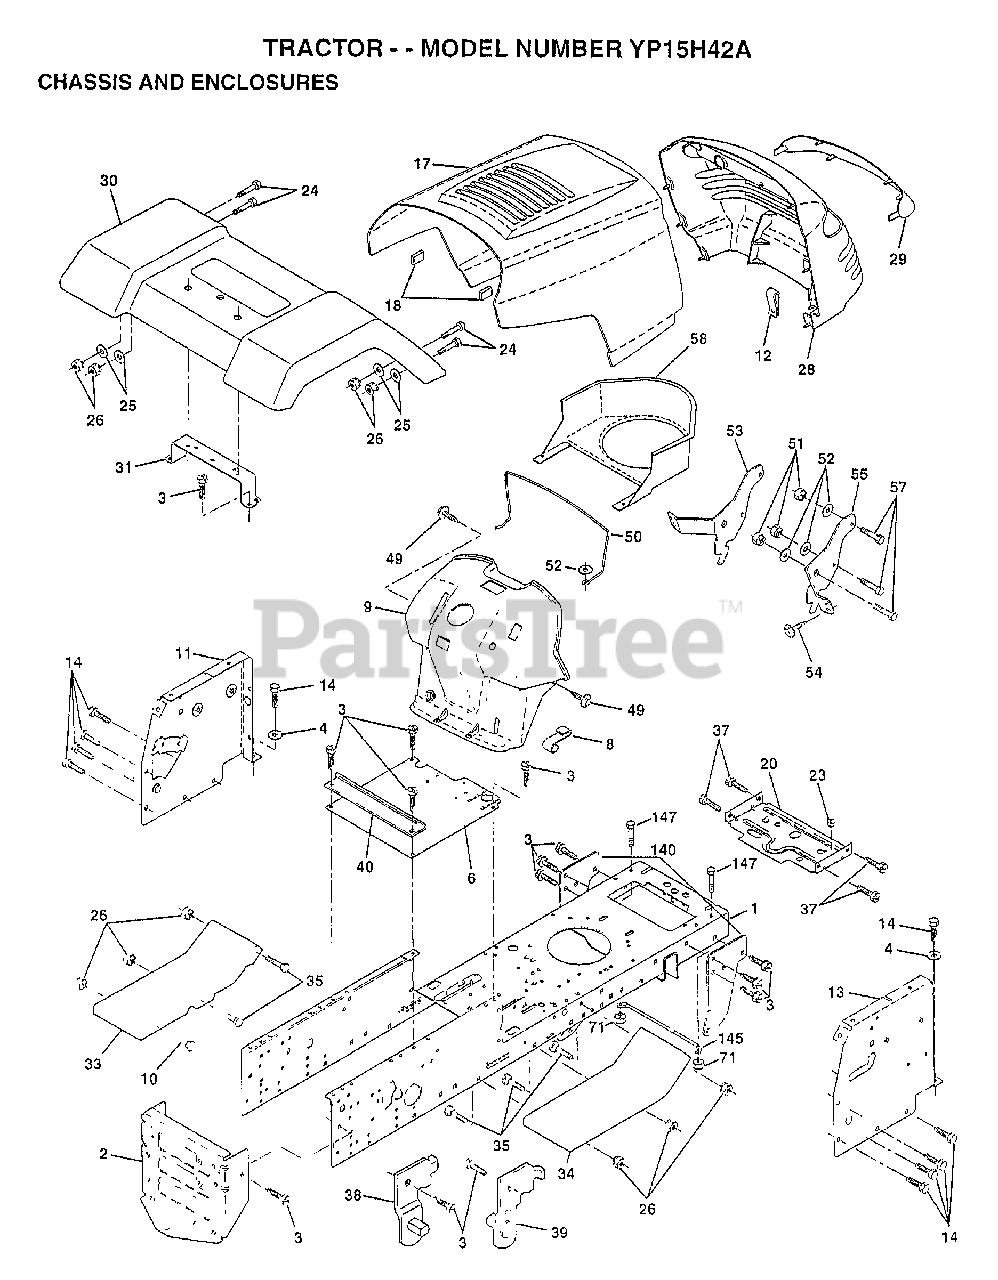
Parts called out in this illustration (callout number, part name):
1	CHASSIS ASM
3	SCREW
4	WASHER
6	SADDLE
8	CLIP.RETAINER
9	DASH.PRVT.LBL.
11	"PANEL-DASH,LH"
12	CLIP.TINNERMAN
13	"PANEL-DASH,RH"
14	SCREW LT
20	"PLATE-MTG,BATT/FU"
24	BOLT
25	WASHER
26	NUT
28	GRILL
29	LENS.EURO.W/DECAL
31	BRACKET SUPT FEND
33	FOOTREST PNT LH
34	FOOTREST.RH.LT/GT
35	BOLT
37	SCREW LT
38	BRACKET ASM LH
39	BRACKET ASM RH
40	SPACER FENDER LT
49	SCREW HEX CRT
50	"ROD SUPPORT,DASH"
51	NUT
52	WASHER
53	BRACKET.GRILLE.LH
55	BRACKET.GRILLE.RH
58	AIR DUCT
140	BRKT SUSPENSION
145	"ROD POVOT,CHASSIS"
147	BOLT LT
